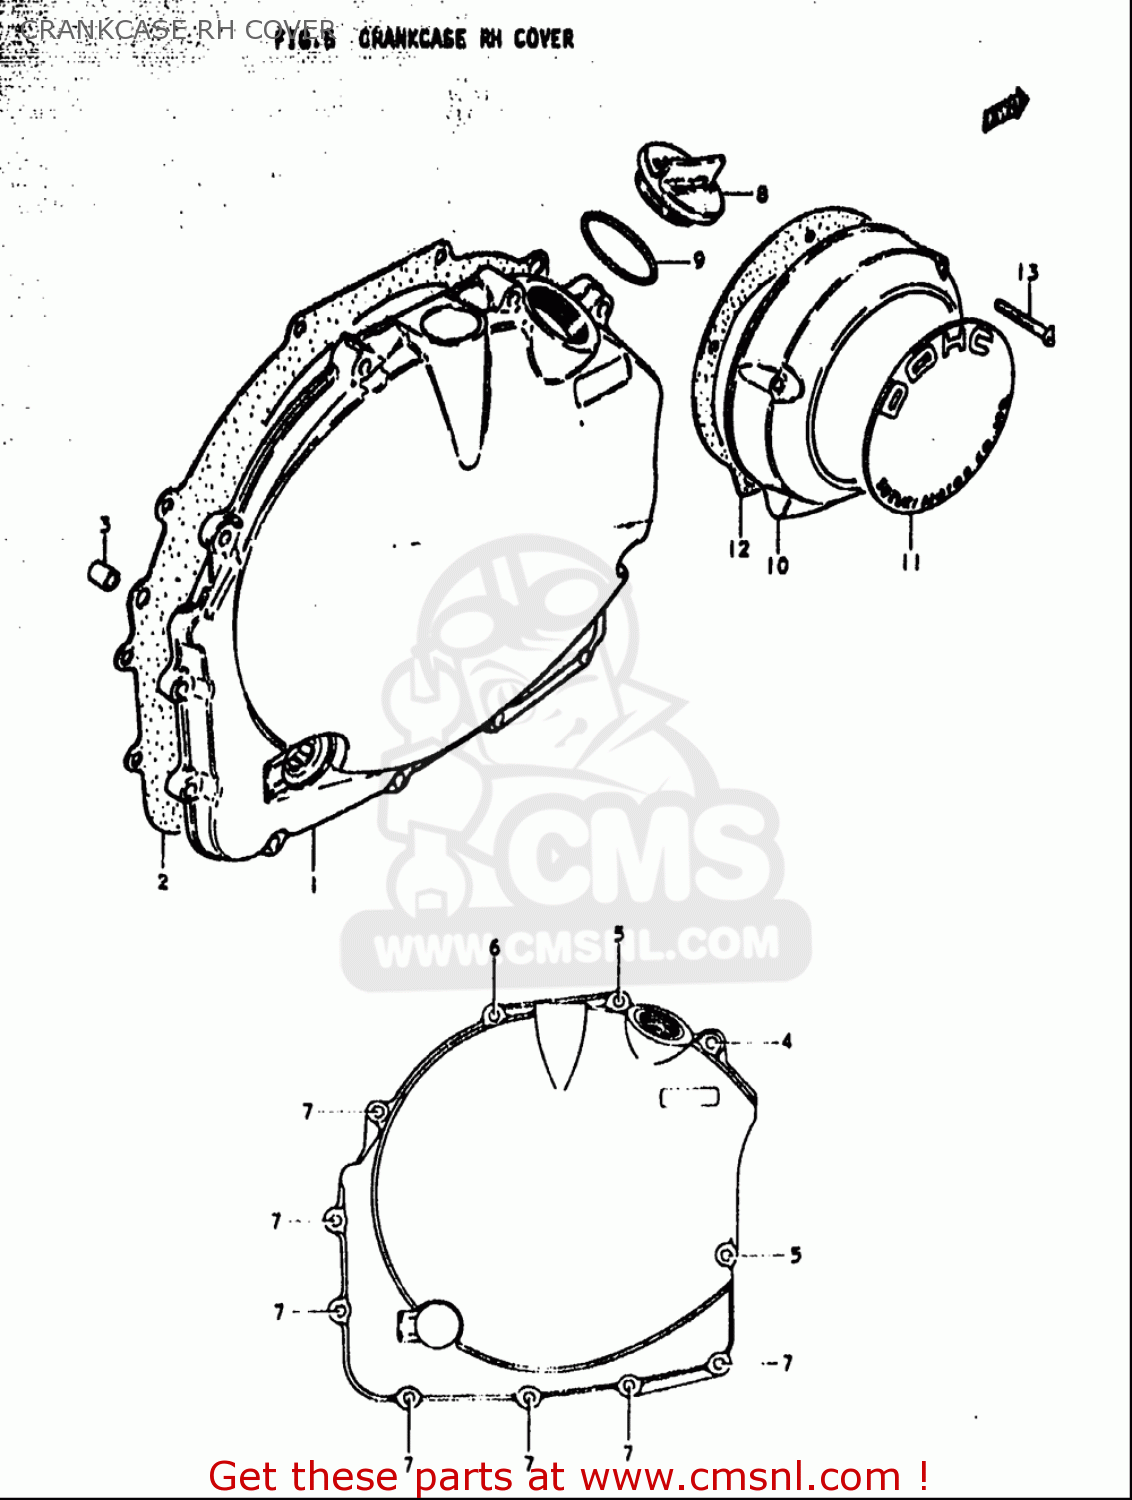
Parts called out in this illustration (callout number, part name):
2	GASKET,CLUTCH COVER (NAS)
3	PIN
4	SCREW
5	SCREW
6	SCREW
7	SCREW
8	PLUG SET
9	O RING(D:2.2,ID:32)
10	COVER,CONTACT BREAKER
11	EMBLEM,CONTACT BREAKER COVER
12	GASKET,CONTACT BREAKER COVER (NAS)
13	SCREW
